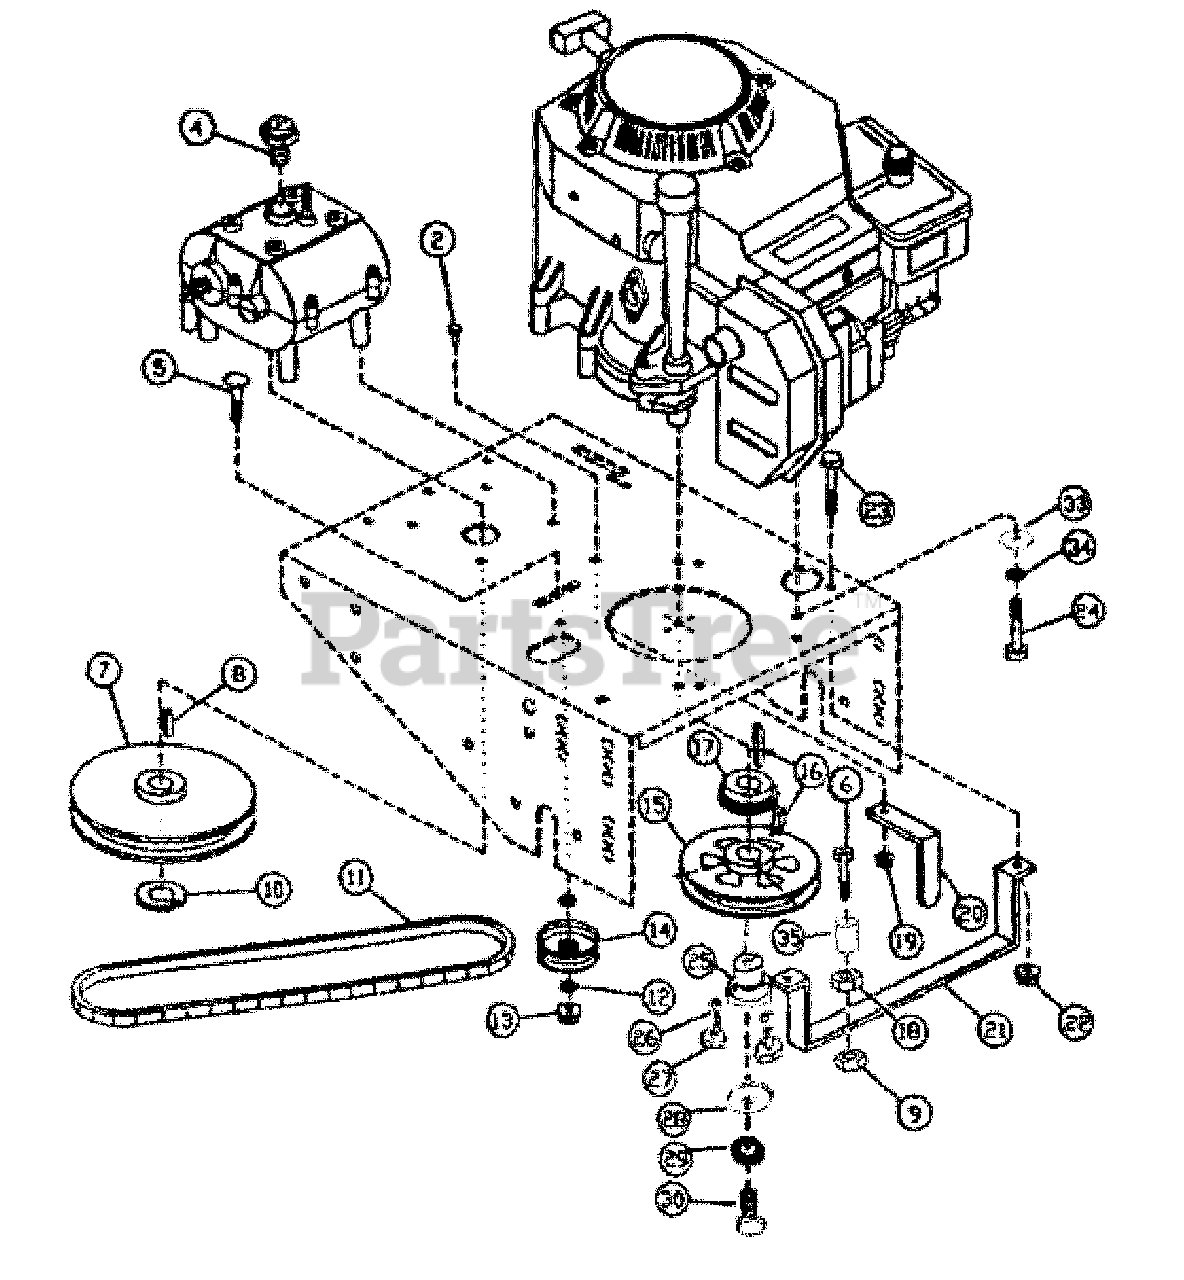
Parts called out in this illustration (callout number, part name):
2	200-045 BOLT M6`20
4	100-055 NEUTRAL SWITCH
5	200-046 BOLT M10`45
6	M10X1.5X60 HHB GR8.8
7	100-063 PULLEY TRANS
8	100-117 WOODRUFF KEY
9	200-006 NYLON NUT M10
10	200-047 SNAP-RING -10 PACK
11	100-064 TRANS. BELT
12	WASHER, 3/8 STD FLAT
13	200-006 NYLON NUT M10
14	100-065 IDLER PULLEY III
15	100-025 PULLEY SINGLE
16	100-066 KEY 6.35`6`25
17	100-067 PULLEY INPUT
18	200-016 NUT FLANGE M10
19	200-009 NYLON NUT M6
21	100-069 BELT GUIDE IV
23	200-048 HEX BOLT M8`20
24	200-049 HEX BOLT M8`40
25	100-026 H-BUSHING
26	5/16HELICAL L-WASHER
27	M8X1.25X30MM HHB
33	5/16STD FLAT WASHER.
34	5/16HELICAL L-WASHER
35	148-014 BUSHING
